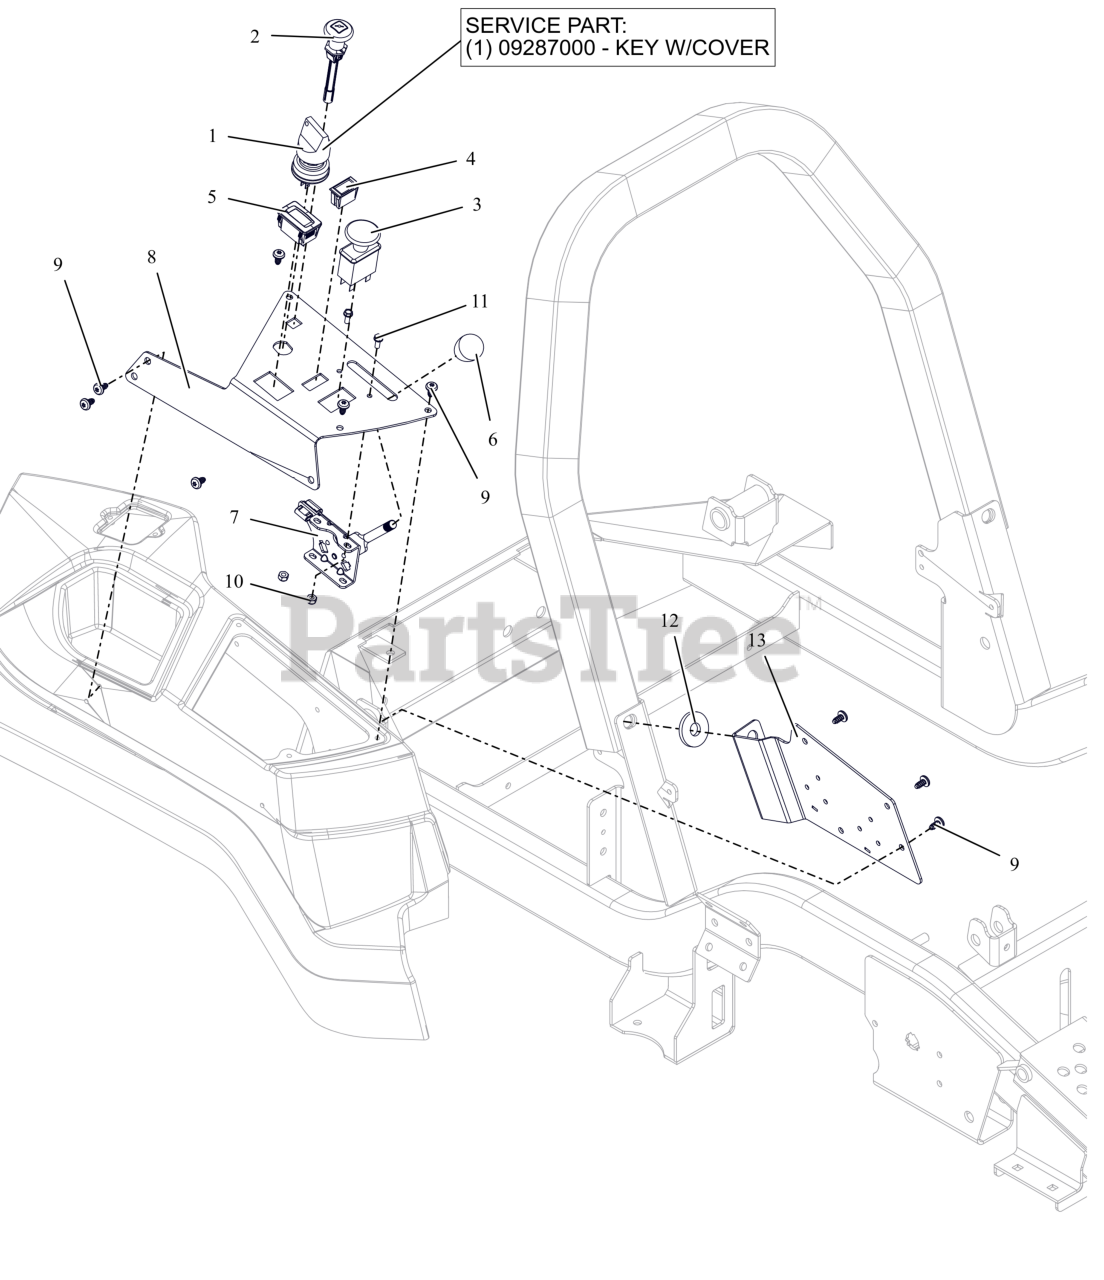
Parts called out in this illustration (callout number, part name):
1	SWITCH, IGNITION
1	KEY, W/ SHIELD
2	CABLE - CHOKE, SNAP-IN
3	SWITCH, CLUTCH
4	SWITCH,BLANK
5	HOUR METER
6	KNOB-CONTROL-BLACK .38-16X.50
7	CABLE, PRO THROTTLE CONTROL
8	PLATE, APEX CONTROL PANEL
9	SCR-PAN .25-15X.50 6L H/LZB500
10	NUT-LK-NYL #10-24 G2 ZCC
11	BLT, HWH #10-24X.50 ZCC
12	WSHR-FL-STL 0.562X1.5X0.187 ZCC
13	BRKT, FENDER/RELAY MOUNTING
